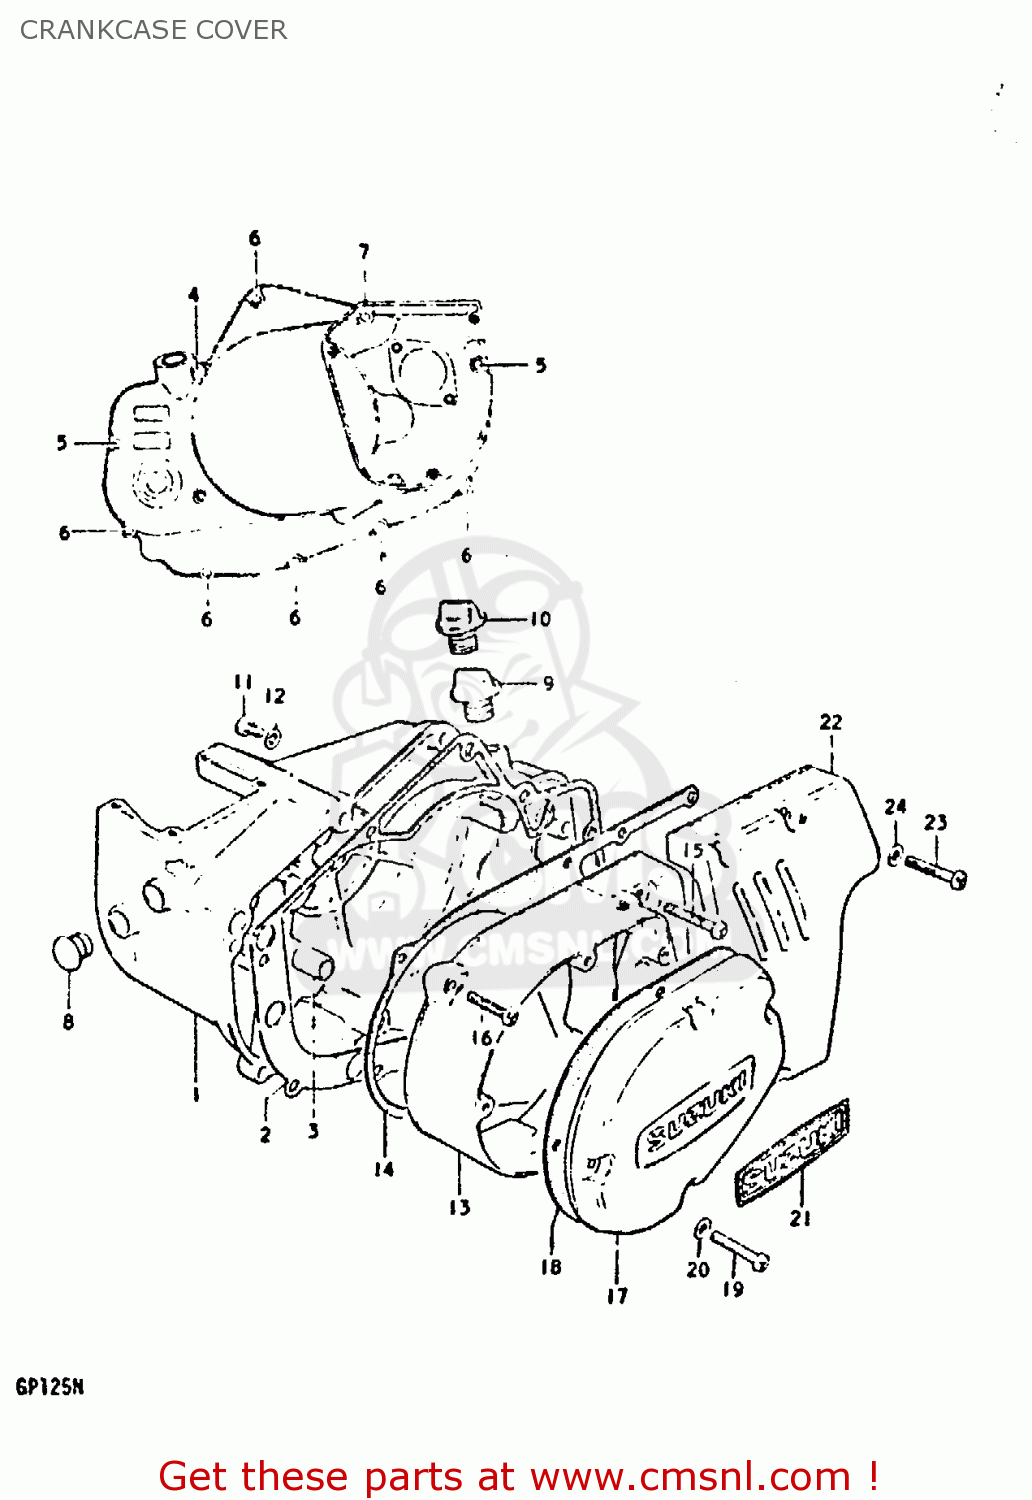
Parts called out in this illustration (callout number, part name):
1	COVER, CLUTCH
2	GASKET, CLUTCH COVER (MCA)
3	PIN
4	SCREW
5	SCREW
6	SCREW
7	SCREW
8	Plug
9	PLUG
10	PLUG,OIL FILTER
11	SCREW(6X10)
12	GASKET(6.2X11X1) (NAS)
13	COVER, MAGNETO
14	GASKET (MCA)
15	SCREW (6X35)
16	SCREW
17	CAP, MAGNETO INSPECTION
18	GASKET,MAGNETO INSPECTION CAP (NAS)
19	SCREW
20	WASHER
22	COVER, ENGINE SPROCKET
23	SCREW (6X35)
24	WASHER
